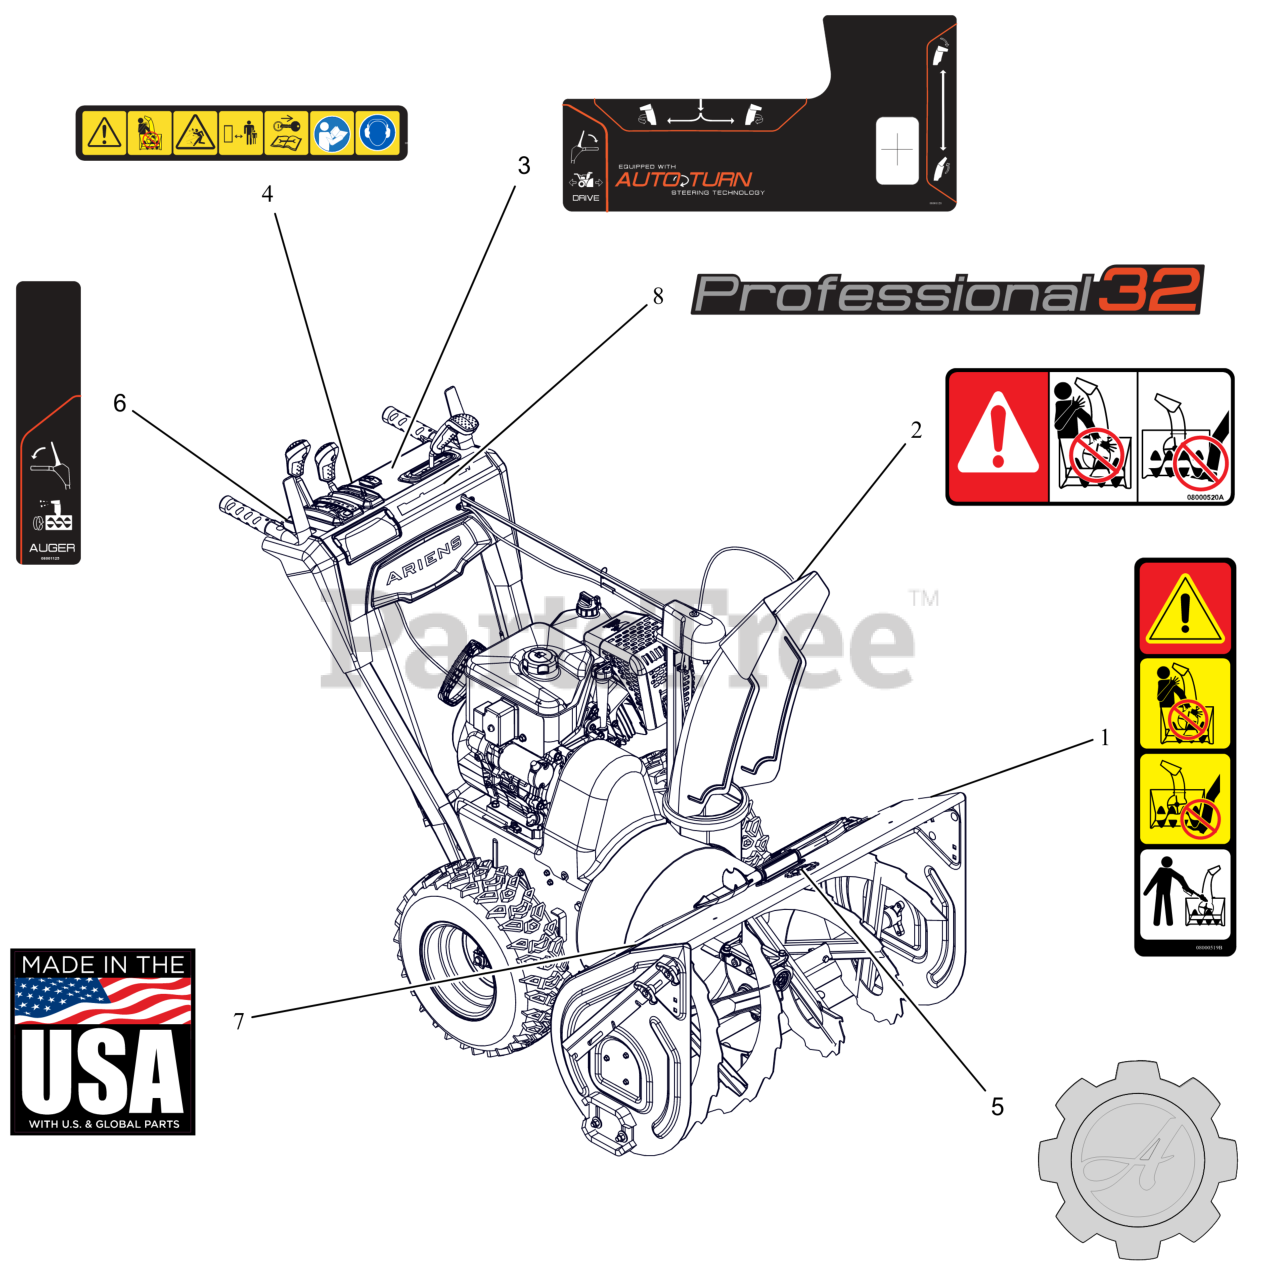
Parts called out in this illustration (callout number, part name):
1	DECAL, DANGER - ROTATING PARTS
2	DECAL, DANGER
3	DECAL,CONTROL-LG QT2
4	DECAL,DASH - SAFETY
5	DECAL, ARIENS-GEAR BADGE -THK
6	DECAL,CONTROL-RH CONTROL
7	DECAL, MADE IN USA
8	DECAL, DASH - PRO 32
